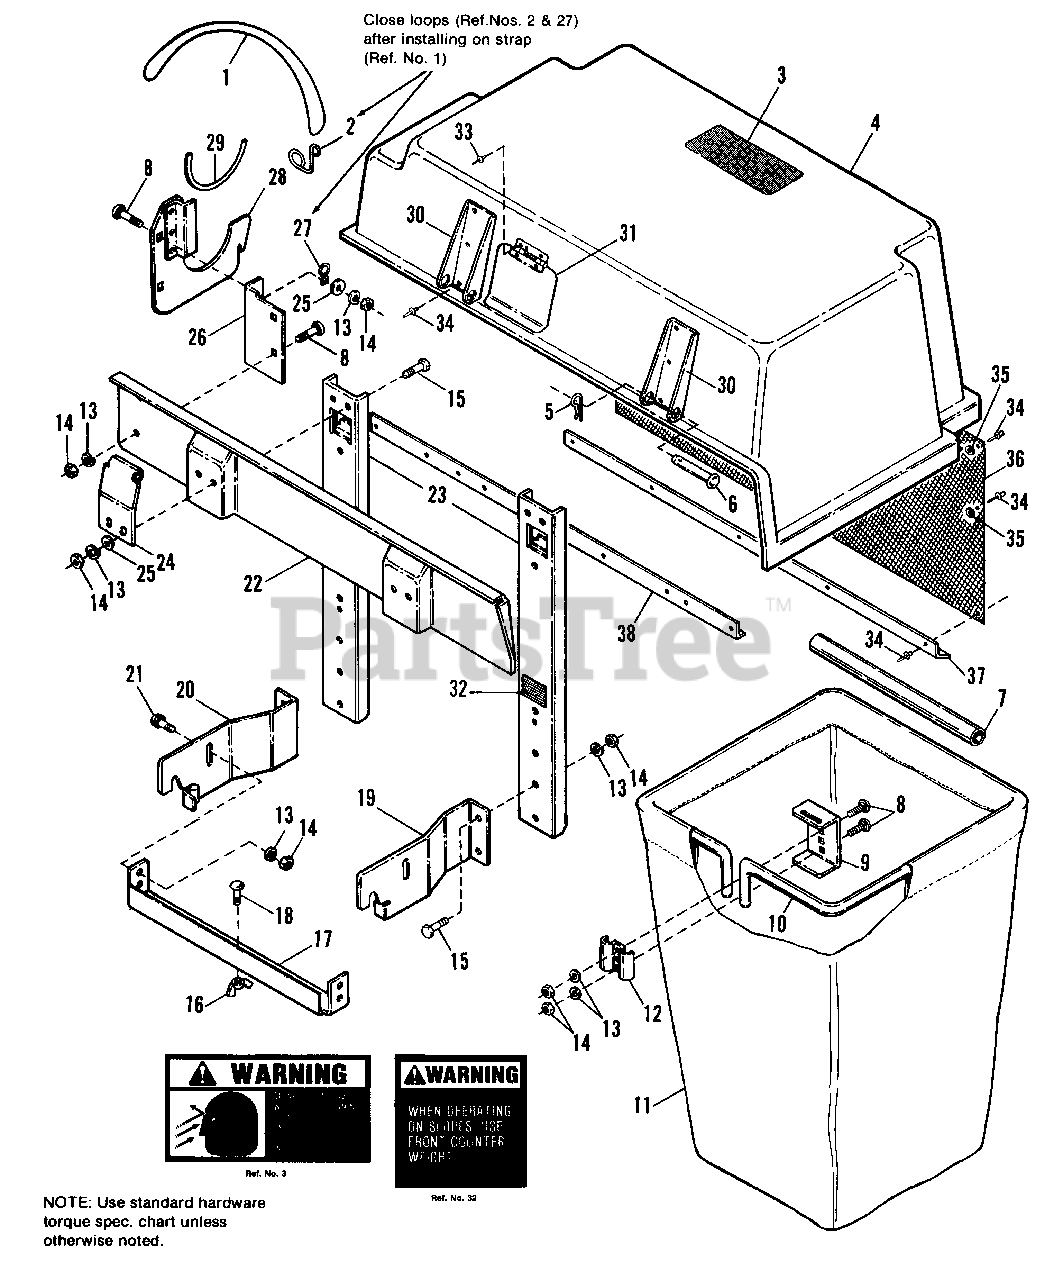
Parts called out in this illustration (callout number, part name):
2	HOOK, Strap
3	DECAL, Warning
4	COVER ASSY.
5	CLIP, Hair Pin
8	BOLT, Carriage, 5/16-18 x 7/8
13	LOCKWASHER, 5/16
14	NUT, Hex, 5/16-18
15	CAPSCREW, Hex, 5/16-18 x 7/8
16	NUT, Winglock, 5/16-18
17	BRACE, Lower
18	BOLT, Carriage, 5/16-18 x 1
19	SUPPORT, L.H.
20	SUPPORT, R.H.
21	SCREW, Hex, Whizlock, Flange, 5/16 x 3/4
22	SUPPORT PLATE, Cover
23	BRACE, Upper
24	HINGE, Plate
25	WASHER, 11/32
26	MOUNT, Saddle Bracket
28	BRACKET ASSY., Saddle
30	BRACKETS, Hinge
31	DOOR (with hinge)
32	DECAL (Catcher Frame)
35	WASHER, Rivet
38	BRACKET, Front Cover
